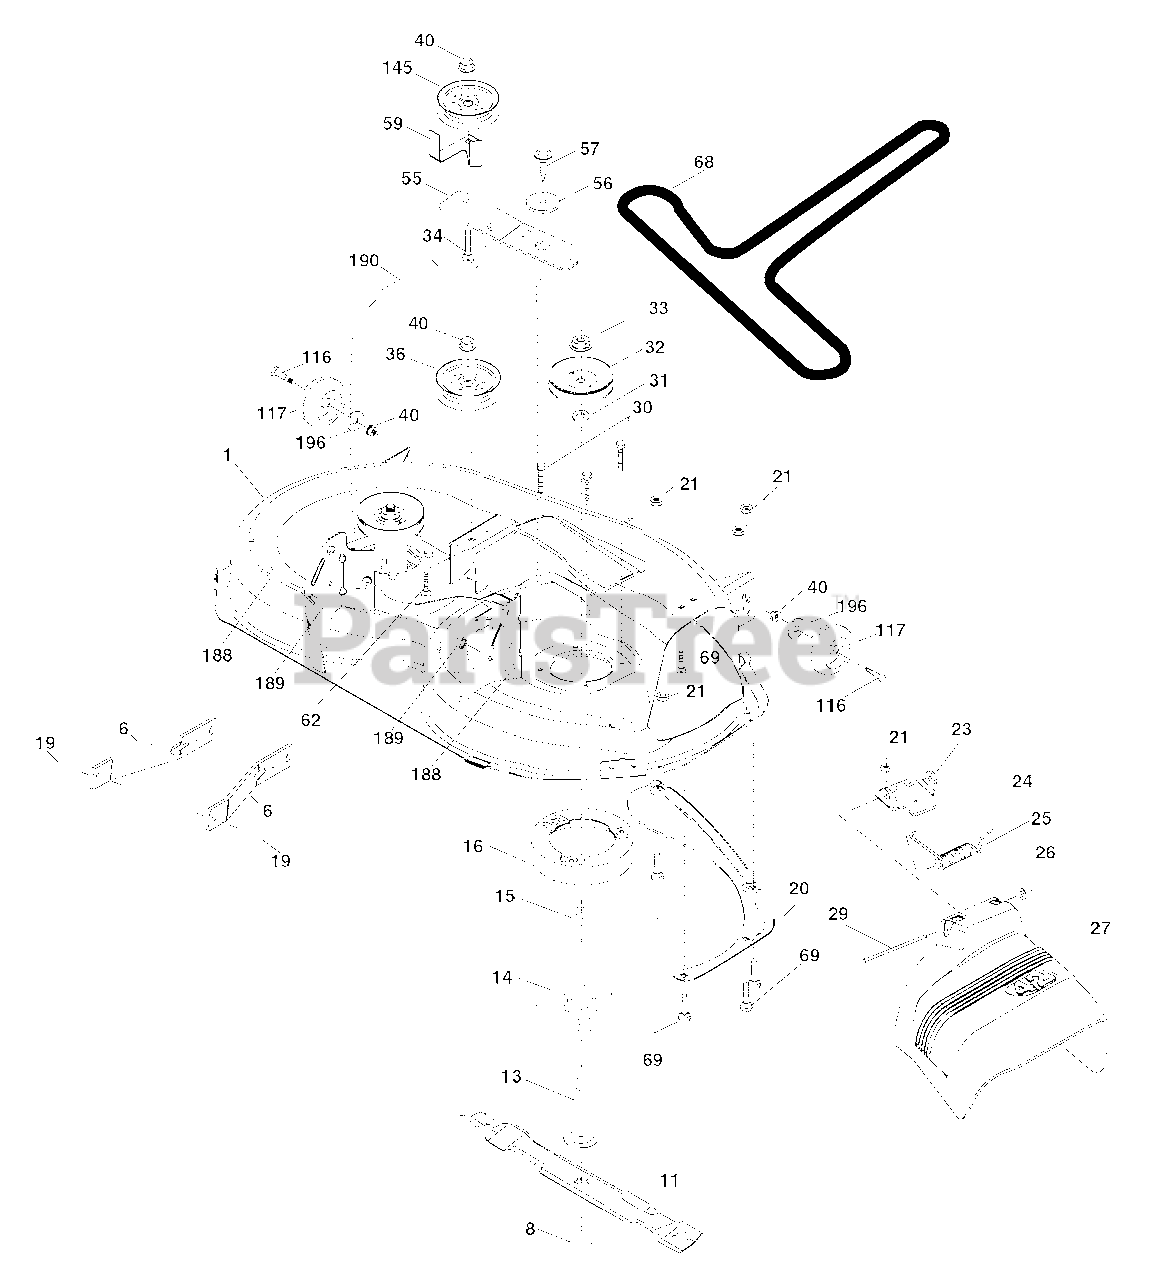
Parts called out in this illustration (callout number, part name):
1	Mower Housing
6	Arm Suspension
8	Bolt/Washer asm 7/16-20 unf
11	Blade, 42" Hi-Lift
11	Blade, 42" Mulching Std
11	Blade, 42" Mulching Premium
13	Shaft Assembly, Mandrel
14	Housing, Mandrel
15	Bearing, Ball, Mandrel
16	Stripper, Mower Deck
19	Bolt, Shoulder
20	Baffle, Vortex
21	Nut, Crownlock 5/16-18 unc
23	Bracket, Deflector
24	Cap, Sleeve
25	Spring, Torsion, Deflector
27	Shield, Deflector
29	Rod, Hinge
30	Screw Thdrol Rolling Wsh Hd
31	Washer, Spacer
32	Pulley, Mandrel
33	Nut, Toplock, Flanged
34	Bolt Carr Sh. 3/8-16 x 1-1/2 Gr. 5
36	Pulley, Idler, Flat
40	Nut, Lock Flg. 3/8-16 unc
55	Arm, Idler
56	Spacer, Retainer
57	Screw 3/8-16 x 1
59	Guard, Tuv Idler
62	Bolt Rd Hd Sq Nk 3/8-16 unc x 2
69	Bolt
116	Bolt, Shoulder
117	Wheel, Gauge
145	Pulley Idler
188	Stud Fastener
189	Nut Lock Hex Flange
190	Spring Mower Drive
196	Washer 13/32 x 1-1/4 x 12 Ga.
196	Mandrel Assembly
196	Replacement Mower, Complete
